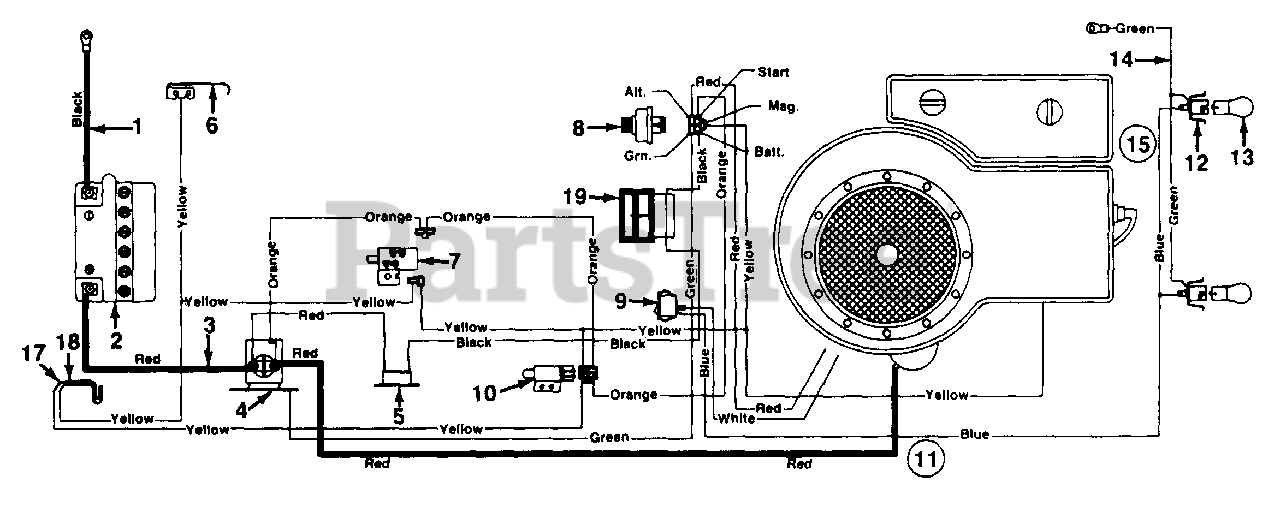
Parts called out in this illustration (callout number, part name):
1	Ground Wire
2	Battery
3	Electric Wire - 8.0" Lg.
4	Solenoid
5	Circuit Breaker
6	Spring Switch (Reverse)
7	Safety Switch (Deck)
8	Ignition Switch
9	Light Switch
10	Safety Switch (Clutch)
11	Harness (B&S)
12	Socket (Sq. Headlights)
13	Bulb (Sq. Headlights)
14	Ground Wire
15	Headlight Harness (Tec.)
17	Safety Switch (Seat)
18	Safety Switch (Seat)
19	Ammeter
